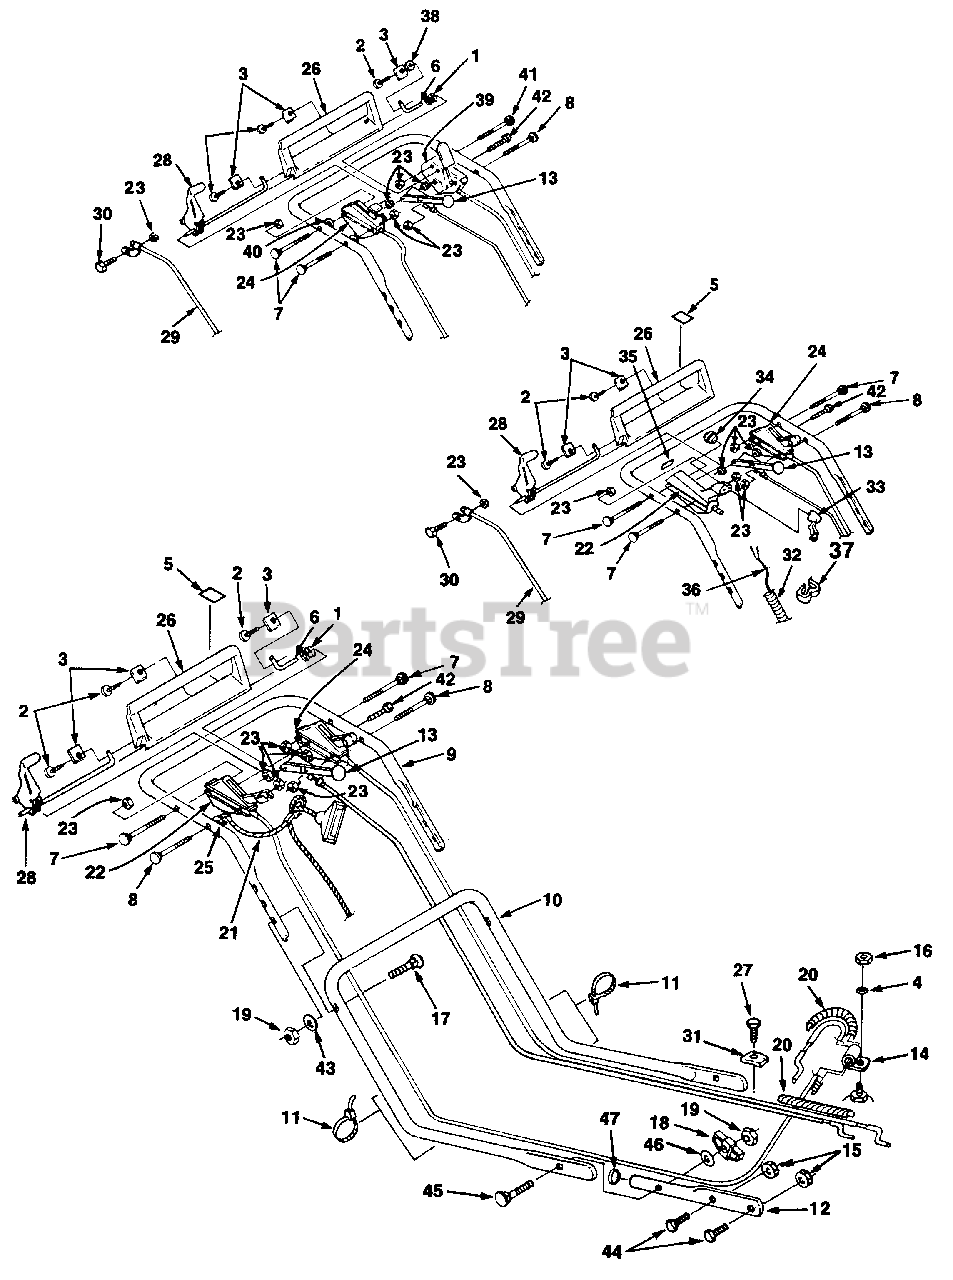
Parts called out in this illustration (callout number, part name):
1	SPRING-Compression
2	SCREW-1/4-10 x 5/8"
3	CLAMP-Pivot shaft
4	WASHER-Lock 1/4"
5	DECAL-Warning
6	SHAFT-Pivot
7	BOLT-Sq. nk.
8	BOLT-Sq. nk.
9	HANDLE-Upper
10	HANDLE-Lower
11	CABLE-Tie
12	STUB-Handle mtg.
13	SHIFT-Gear
15	NUT-Flange 5/16-18
16	NUT-Hex 1/4-20
17	BOLT-5/16-18 X 1 1/2'
18	KNOB-Handle
19	NUT-Hex 5/16-18
20	COVER-Cable
21	GRIP-Restraint
22	ENGINE CONTROL
23	NUT-Lock 1/4-20
24	CONTROL-Throttle
25	WASHER
26	BAIL-Brake control
27	SCREW-Hex 1/4-20 X 5/8"
28	TRACTION LEVER ASSY
29	CABLE-Traction control
30	SCREW-1/4-20 X 1 1/2"
32	COVER-Control cable
33	HOUSING-Switch
36	HARNESS-Wiring
37	CLIP-Cover
38	WASHER-Plain 1/4"
39	CONTROL-BBC
40	SPACER
41	BOLT-Sq. nk.
42	SCREW
43	WASHER-Lock 5/16-18
44	BOLT-Hex 5/16-18 x 1
45	BOLT-Handle joining
46	WASHER-Flat 5/16
